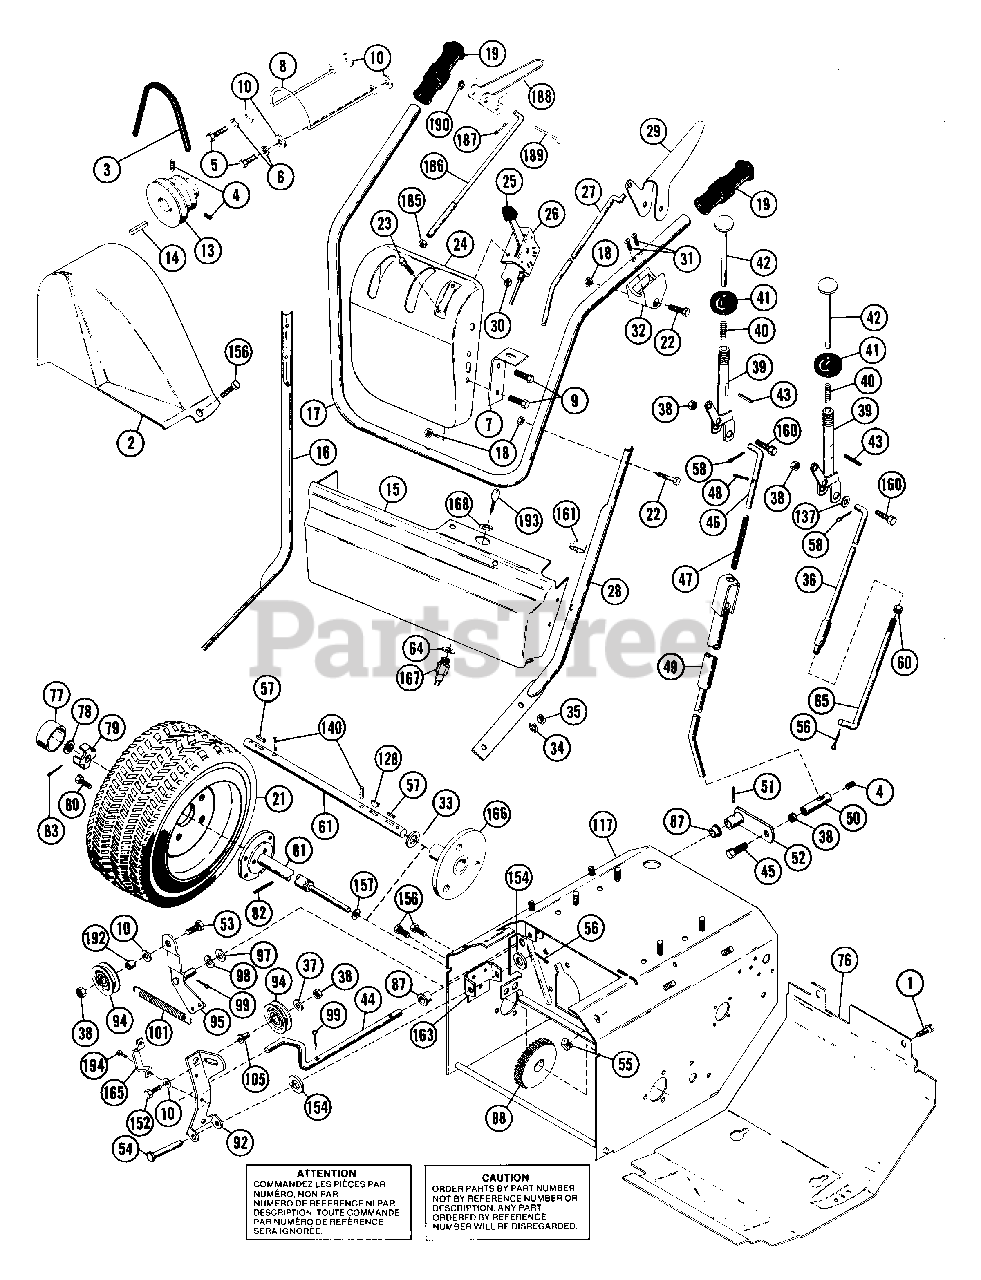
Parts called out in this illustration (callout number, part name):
1	BLT-SERHFWH .31-18X.50 PL
2	BELT COVER
3	BELT,3L 33.00 RAW LAM C-L2089
3	V-BELT, 3L-RAW EDGE
4	SCR-SET .32-18X.38 SKHCUPNL OH
5	BLT-HEX .31-24X.75 PL GR5
6	WSHR-LK .312X.097 PL HVY
8	BELT FINGER
9	BLT-HEX .25-20X.63 PL GR2
10	WSHR-FL-STL .38X.875X.083 PL
13	ENGINE SHEAVE
13	SHEAVE, ENGINE
14	KEY-STR .25X1.75X.25
16	R H LOWER HANDLEBAR
17	UPPER HANDLEBAR ASSEMBLY
17	UPPER HANDLEBAR
18	NUT-LK-CTR .250-20 PL
19	GRIP
21	TIRE & WHEEL ASSEMBLY CARLISLE
21	TIRE 4.10/3.50X6
21	TUBE
21	WHL 6 IN O.D.
21	WHEEL ASSEMBLY
21	TIRE
21	WHL
21	TERRA TIRE & WHEEL ASSEMBLY
21	TIRE 16X6.50-8 2 PLY
22	BLT-HEX .25-20X1.50 PL GR5
23	SCR-MCH 10-24X.50 SLRH PL
24	DASH ASSEMBLY
26	THROTTLE CONTROL
27	CLUTCH ROD
28	L H LOWER HANDLE BAR
29	CLUTCH HANDLE ASSEMBLY
30	NUT-KEPS 10-24 PL
31	SCR-TAP 12-14X1.50 CROVH PL BT
32	HANDLE PIVOT
33	WSHR-FL-STL .755X1.375X.125
33	WSHR-FL-STL .880X1.380X.062
34	WSHR-LK .375X.115 HVY PL
35	NUT-HEX .375-16
36	SHIFT ROD UPPER
37	WSHR-FL-STL.312X.734X.065PL
38	NUT-LK .312-18 GR A PL
39	CONTROL HANDLE
40	SG-COMP ??X.44X?? WLD 10
41	SHIFT BALL
42	SHIFT RELEASE HANDLE
43	PIN-ROLL .188X1.75
44	ACUTATION SHAFT
45	BLT-HEX .31-18X.75 PL GR2
46	CLUTCH ROD
47	SG-COMP .072X.37X10.3 WLD 40
48	PIN-ROLL .125X.75
49	ATTACHMENT CLUTCH ROD
50	ROD ADAPTER
51	PIN-ROLL .156X.75
53	BLT-HEX .31-18X1.00 PL GR 2
54	PIN-CLEV .309X2.25
55	NUT-RETNR .38-16 TINRMAN
56	PIN-COTR .09X.75 PL
57	KEY-FTHR .188X1.25X.187 SAE
58	PIN-COTR .12X.75 PL
60	NUT-HEX .312-24 PL
61	AXLE SHAFT
64	WSHR-LK-INT .625X.045 PL
65	ROD LOWER SHIFT
76	BOTTOM COVER
77	HUB CAP
78	PUSHNUT
79	SPINDLE CUP
80	BLT-WHL .50-20X.75 GR5 PL
81	R H AXLE SHAFT
81	R H AXLE
82	PIN-ROLL .188X1.25
82	PIN-ROLL .188X1.50
83	PIN-COTR .12 X 1.25 PL
87	BSHG-FLG.500X.625X.312X.750NY
88	DIFFERENTIAL ASSEMBLY
88	SPUR GEAR, FELLOWS 35T .750 ID
88	GEAR, SPUR
92	ARM, IDLER
94	IDLER
95	IDLER ARM
97	WSHR-FL-STL .382X.812X.023 PL
98	WAVE WASHER .406X.750X.063FH
99	PIN-COTR .12X1.0 PL
101	SG-TENS .080X.73X3.06 WLD 20
105	SPCR, BRG .315X.50X.688X.281
117	FRAME - TRACTOR 6 HP
117	FRAME
128	KEY-WDRF .25X.750X.313 SAE91
128	KEY-WDRF .25X.875X.375 SAE A
137	WSHR-FL-STL .382X.812X.062
140	PIN-ROLL .188X1.00
140	PIN-ROLL .188X1.25
152	BLT-HEX .31-18X1.25 PL GR2
154	WSHR-FL-STL .380X.626X.033
156	BLT-SERHFWH .25-20X.50 PL
157	WSHR-FL-STL .880X1.380X.062
157	WSHR-FL-STL 1.140X1.718X.134
160	BLT-HEX .31-18X2.00 PL GR2
163	BRACKET
165	RETURN CLIP
166	WHEEL HUB
167	KEY SWITCH
168	NUT .625-32 ALUM
185	NUT-HEX .250-20 PL
186	UPPER ROD INTERLOCK
187	PIN-COTR .06X.50
188	HANDLE INTERLOCK
189	PIN PIVOT
190	PUSH NUT, .25
192	SPACER .50 X .32 X .42
193	KEYS
194	SCR-TAP 10-24X.375 HWH PL TR
